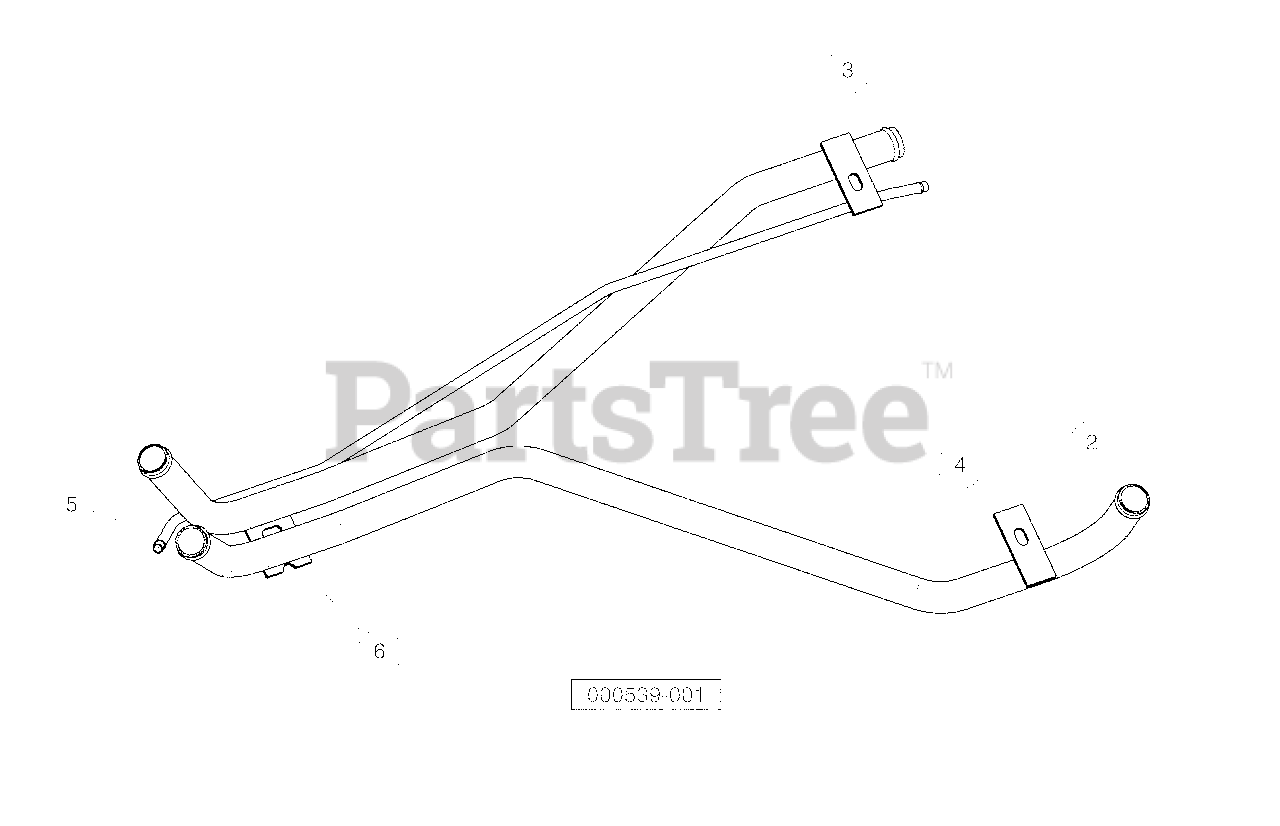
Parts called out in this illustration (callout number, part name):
1	Weldment, Group, Coolant Pipe
2	Pipe, Coolant Upper
3	Pipe, Coolant Lower
4	Tab, Rear Mntg, Coolant Pipe.
5	Pipe, Vent, Coolant
6	Tab, Cooling Pipe Mount
